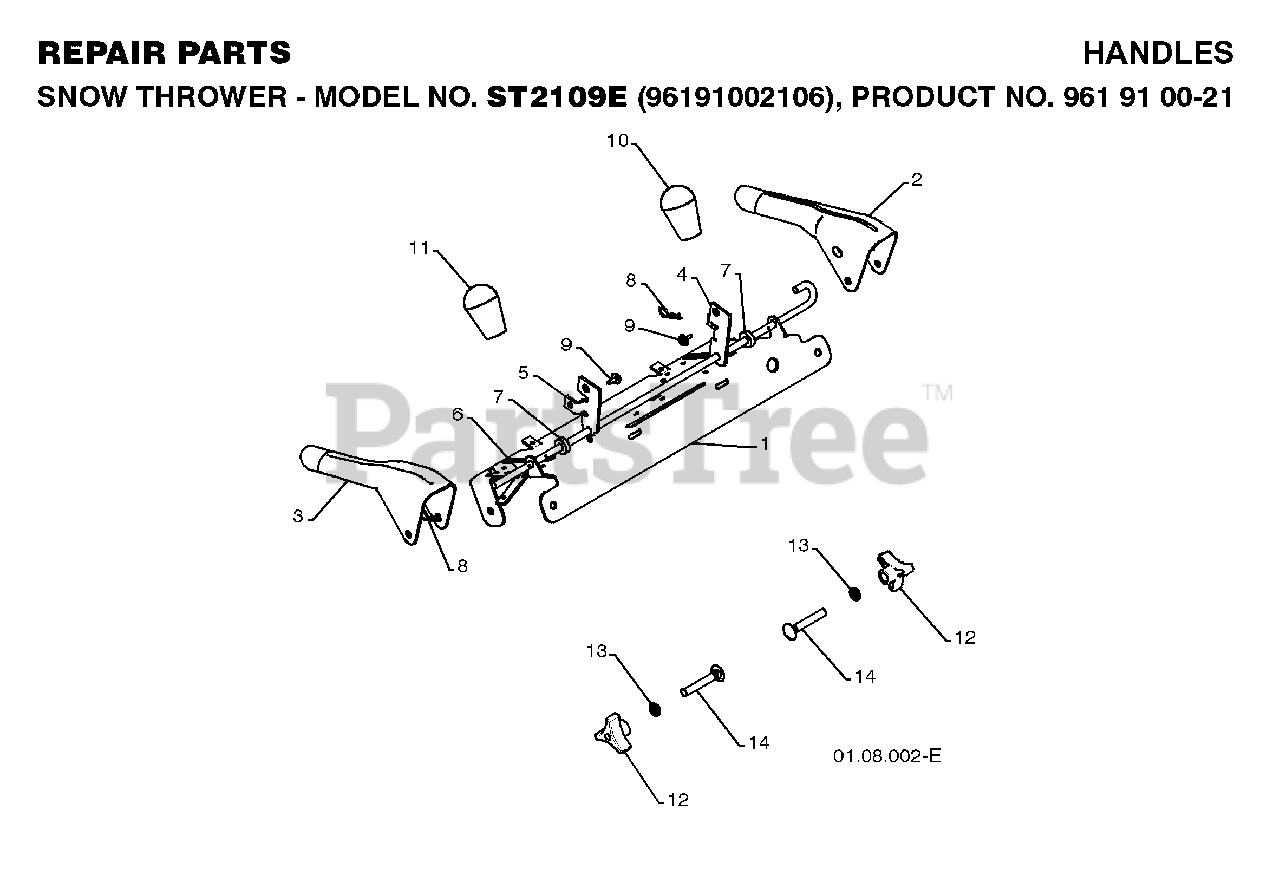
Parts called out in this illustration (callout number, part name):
1	PANEL.CONTROL.PNT.BLACK
2	LEVER.CONTROL.LH.PNT
3	LEVER.CONTROL.RH.PNT
4	ARM.TRACTION.ROD.YZ
5	ARM.IMPELLER.ROD.
6	BAIL.CONTROL.INTERLOCK
7	SPACER.CONTROL.LEVER
8	SPRING RETAINER
10	KNOB LEVER, BLACK
11	RED KNOB SHIFTER
12	KNOB.HANDLE.3/8.TRI-POINT.BLAC
14	BOLT 3/8-16 X 2-1/4
